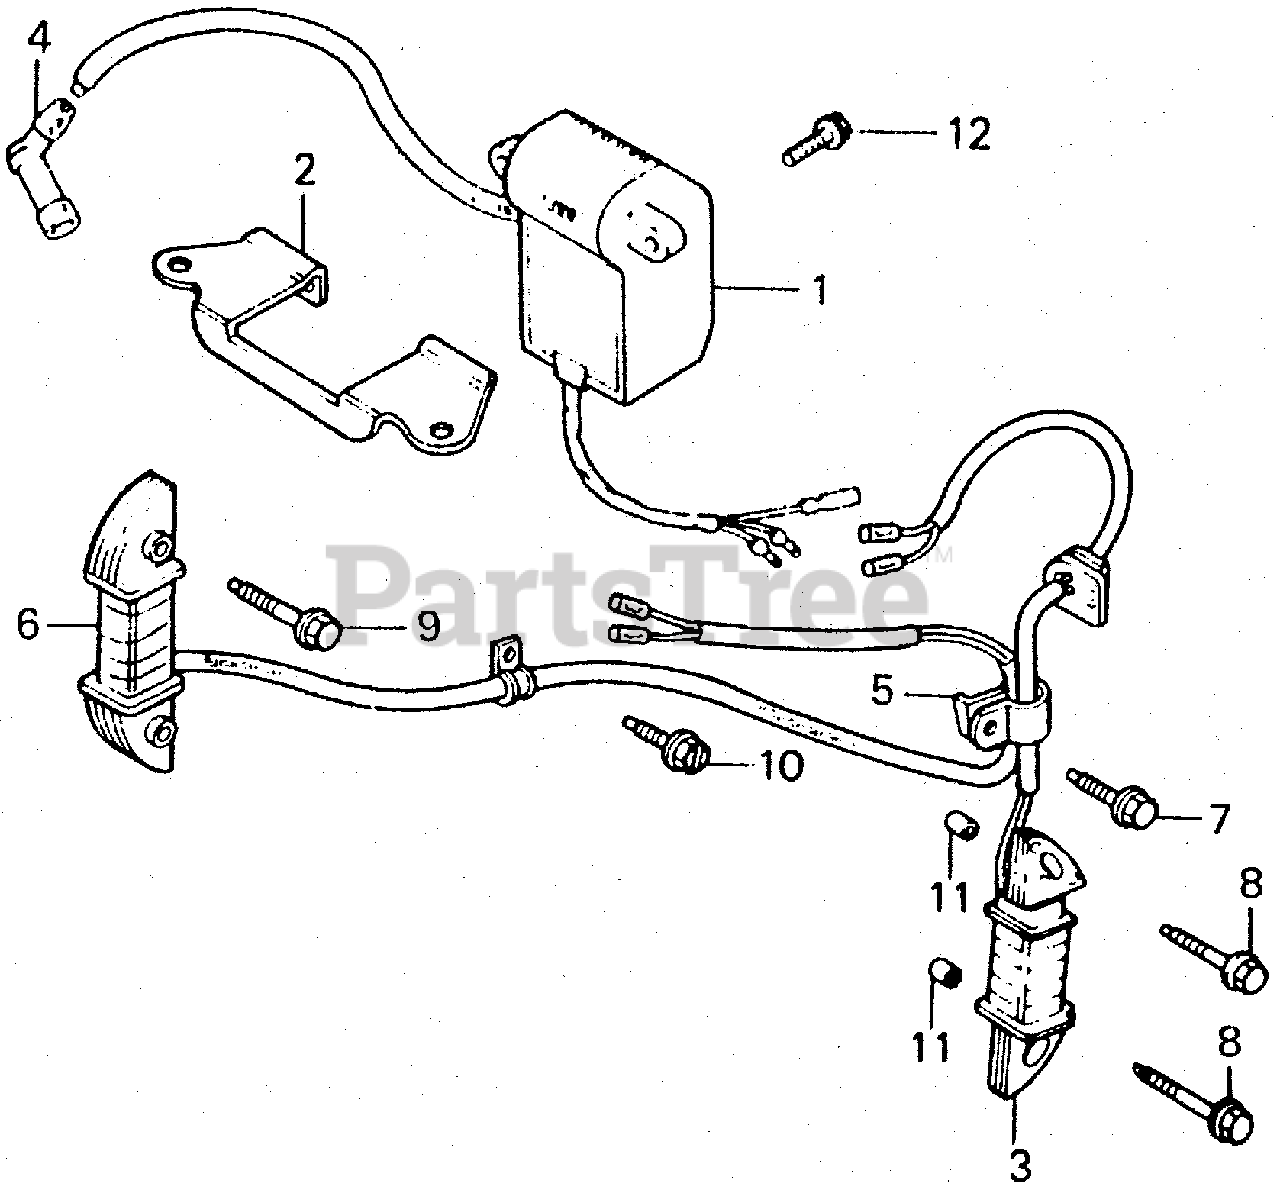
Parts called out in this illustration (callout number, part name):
1	LAMP UNIT, C.D.I.
2	STAY, IGNITION CONTROL MODULE
3	COIL ASSY., EXCITER LAMP (STARTER)(LAMP)
4	CAP ASSY., NOISE SUPPRESSOR
5	CLAMP, IGNITION WIRE
6	COIL ASSY., CHARGE (SILICON RECTIFIER)
7	BOLT, FLANGE (6X12) (CT200)
8	BOLT, FLANGE (6X28)
9	BOLT, FLANGE (6X32)
10	BOLT, FLANGE (5X10)
11	PIN, DOWEL (8X14)
12	BOLT, FLANGE (6X12)
